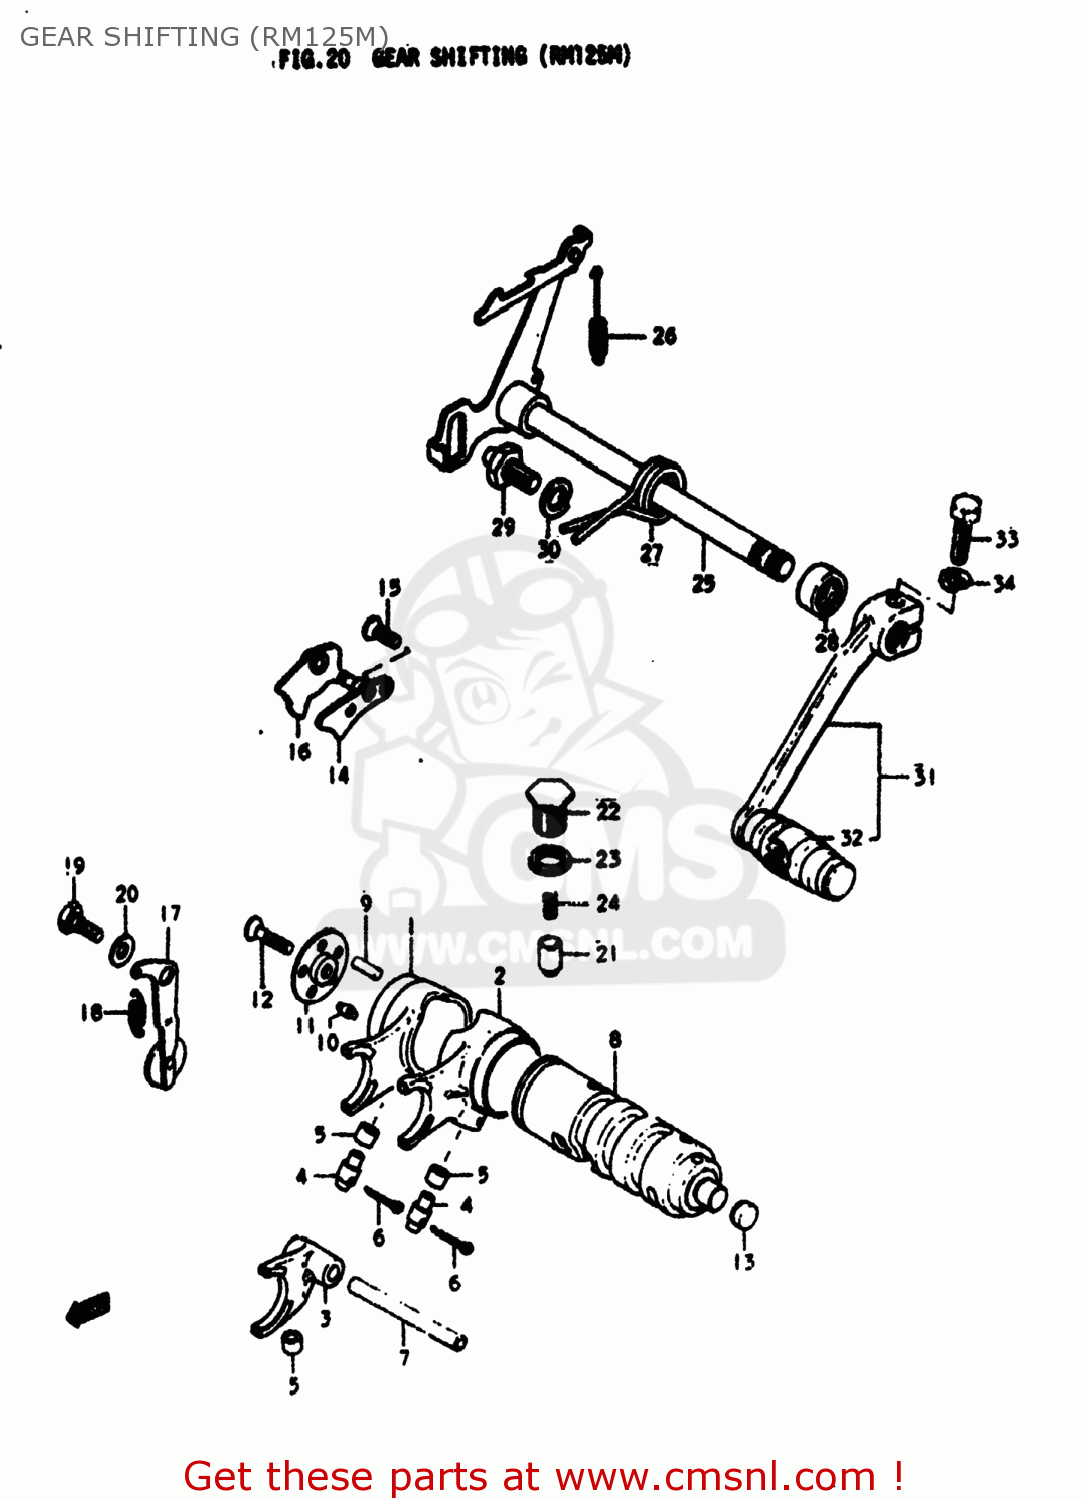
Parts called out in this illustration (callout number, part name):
1	FORK,GEAR SHIFT NO.1
2	FORK,GEAR SHIFT NO.2
3	FORK,GEAR SHIFT NO.3
4	PIN
5	SPACER
6	PIN 25X20
7	SHAFT,GEAR SHIFT FORK
8	CAM,GEAR SHIFT
9	ROLLER(4X13.8)
10	PIN
11	RETAINER,GEAR SHIFT CAM DR PIN
12	SCREW
13	PLUG
14	GUIDE,GEAR SHIFT CAM
15	SCREW
16	PAWL,GEAR SHIFT CAM STOPPER
17	STOPPER,GEAR SHIFT CAM
18	SPRING
19	BOLT(6X16.1)
20	WASHER(6.5X16X2.3)
21	STOPPER,GEAR SHIFTING
22	HOLDER,SHIFTING CAM STOPPER
23	GASKET(14X19.2X2) (NAS)
24	SPRING
25	SHAFT,GEAR SHIFT
26	SPRING
27	SPRING
28	OIL SEAL
29	STOPPER,GEAR SHIFT ARM
30	LOCK WASHER
31	LEVER ASSEMBLY,GEAR SHIFTING
32	RUBBER,GEAR SHIFT PEDAL
33	BOLT
34	LOCK WASHER
